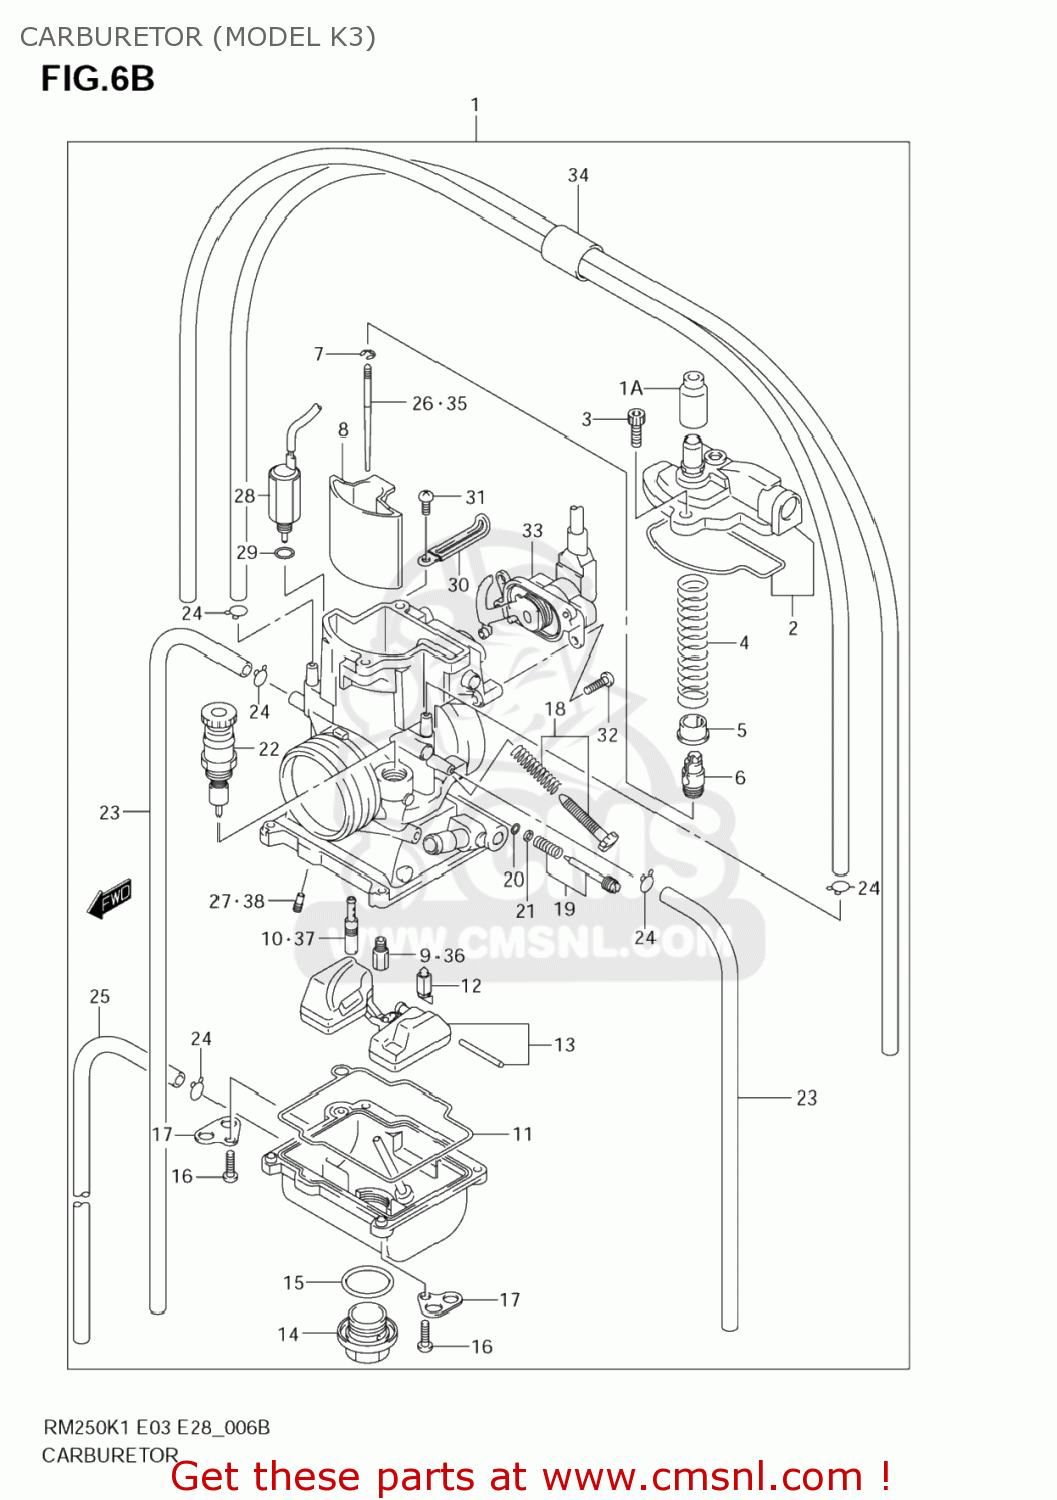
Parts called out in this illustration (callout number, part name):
1	CARBURETOR ASSY
1A	CAP,CARBURETOR
2	CAP SET,TOP
3	SCREW
4	SPRING,THROTTLE VALVE
5	COLLAR,THROTTLE VALVE
6	HOLDER,CABLE
7	CLIP,NEEDLE
8	VALVE,THROTTLE
9	JET,MAIN(175)
10	JET,SLOW(48)
11	GASKET,FLOAT CAHMBER
12	VALVE SET,FLOAT
13	FLOAT SET
14	BOLT,DRAIN
15	O RING
16	SCREW
17	PLATE
18	SCREW SET,STOP
19	SCREW SET,AIR
20	O RING
21	WASHER
22	STARTER VALVE
23	HOSE(4X7X620)
24	CLIP
25	HOSE(3.5X6.5X600)
26	NEEDLE,JET(N8RH)
27	JET,POWER(50)
28	SOLENOID ASSY
29	O RING
30	CLAMP
31	SCREW
32	SCREW
33	SENSOR ASSY
34	CLIP
35	NEEDLE,JET(N2Z
36	JET,MAIN(150)
37	JET,SLOW(35)
38	JET,POWER(45)
